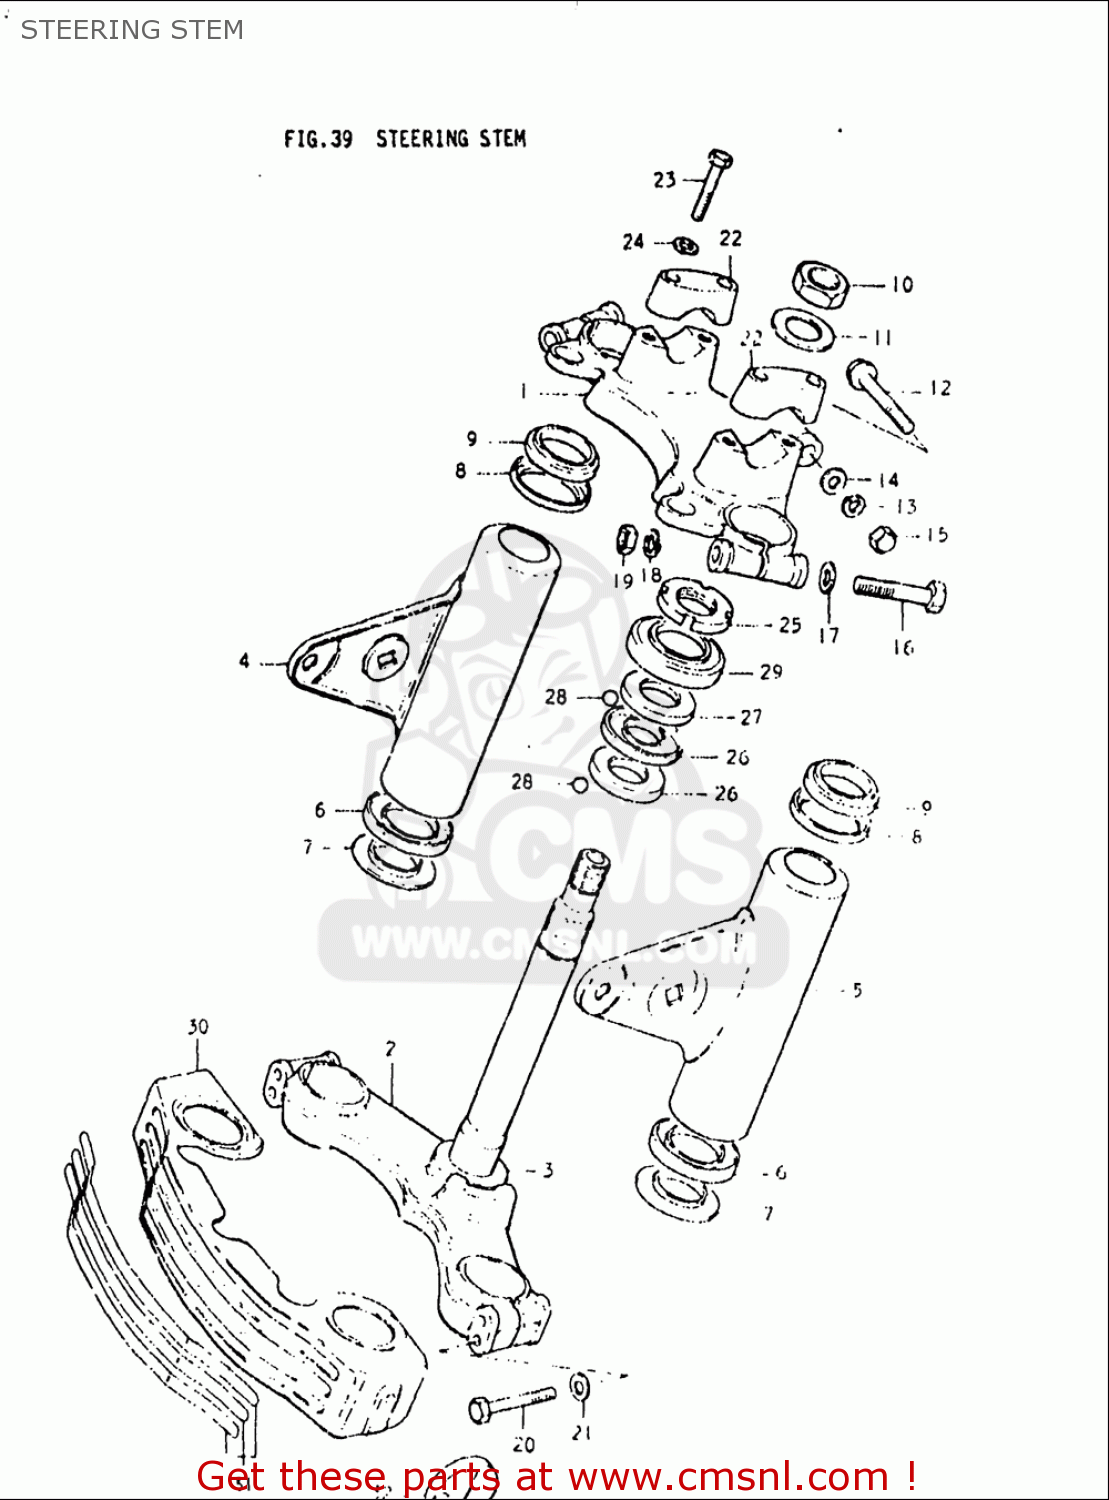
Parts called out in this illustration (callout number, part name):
3	RACE,STEERING OUTER LWR
6	GUIDE
7	CUSHION,HEADLAMP BRACKET
8	GUIDE
9	CUSHION,HEADLAMP BRACKET UPR
10	BOLT(12X20)
11	WASHER(12.5X26X1.6)
13	WASHER,LOCK
14	WASHER
15	NUT
16	BOLT
17	WASHER
18	WASHER,LOCK
19	NUT
20	BOLT
21	WASHER
22	HOLDER,HANDLE UPR
23	BOLT
24	WASHER,LOCK
25	NUT,STEERING STEM(25X44X10)
26	LACE,STEERING INNER LWR
27	LACE,STEERING OUTER UPR
28	BALL
32	REFLEX REFLECTOR,RR
